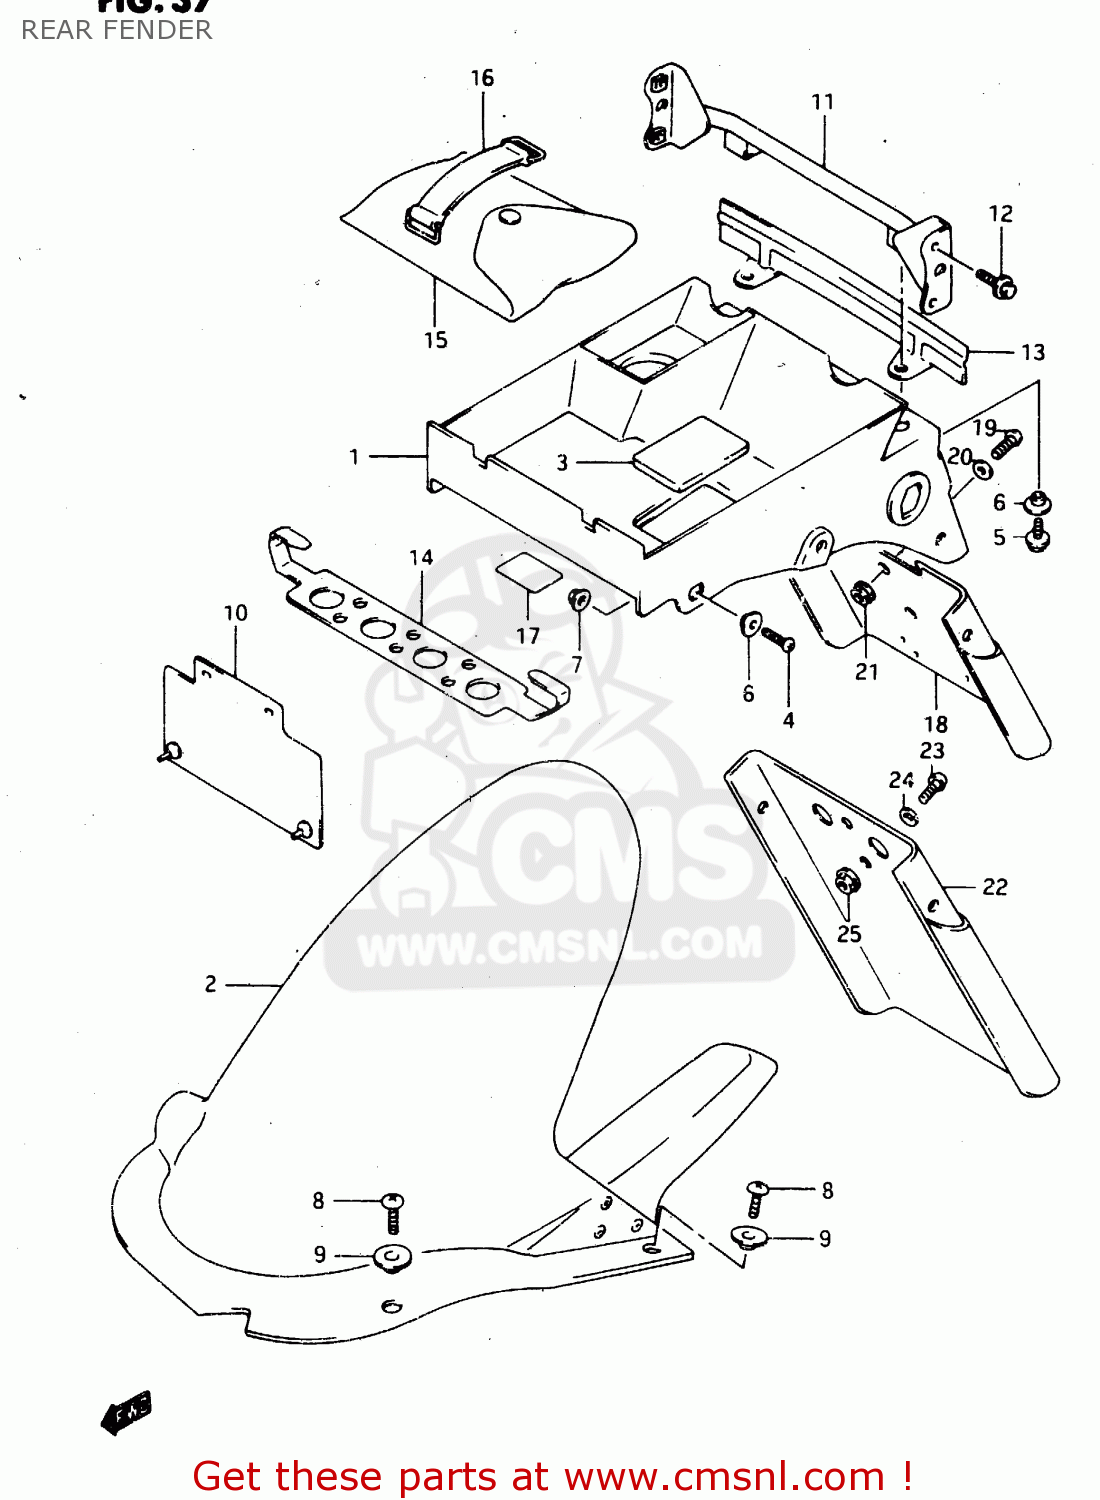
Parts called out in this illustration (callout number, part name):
1	BODY,RR FEND,R
2	FENDER,RR LWR
3	CAP,RR FENDER RR
4	SCREW
5	BOLT
6	WASHER
7	NUT
8	SCREW
9	WASHER
10	MUD GUARD,RR
11	BRACE, REAR FENDER
12	BOLT 6X12
13	PLATE,RR FENDER COVER
14	HOLDER, HELMET
15	TOOL ASSY
16	BAND
17	TAPE,RR FENDER
18	EXTENSION,RR FENDER
19	SCREW
20	WASHER(6.5X16X1.2)
21	NUT
22	MUD GUARD, REAR FENDER
23	SCREW
24	WASHER(6.5X16X1.2)
25	NUT
26	O.M. RGV250 N
